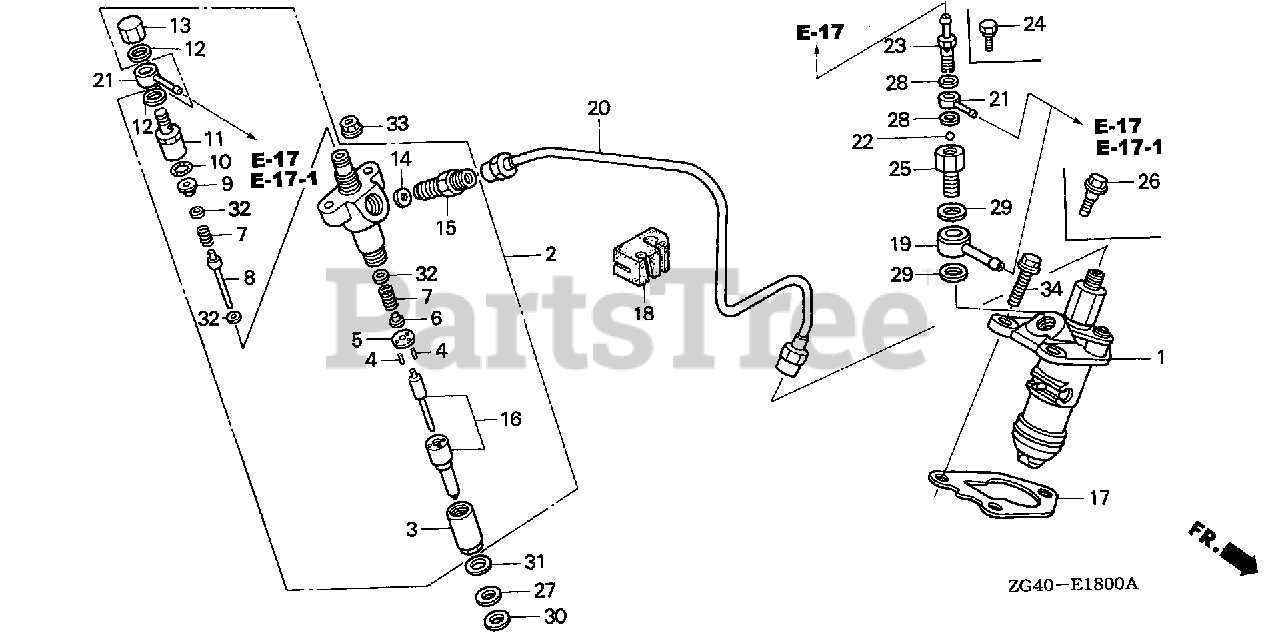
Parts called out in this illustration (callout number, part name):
1	PUMP ASSY., FUEL INJECTION
2	NOZZLE & HOLDER ASSY.
3	NUT, RETAINING
4	PIN (1.78X9.3)
6	SEAT, SPRING (A)
7	SPRING, NOZZLE
9	SEAT, SPRING (B)
15	CONNECTOR, IN.
17	GASKET, FUEL INJECTION PUMP
18	RUBBER, FUEL TUBE CLAMP
19	JOINT, FUEL
20	PIPE A, FUEL
21	JOINT, AIR BREATHER (B)
22	BALL, CHECK
23	BOLT, AIR BREATHER (8X20)
25	BOLT, FUEL JOINT (12X25.5)
26	BOLT, ROTARY TRANSMISSION
27	WASHER, PLAIN (7MM)
28	WASHER (8MM)
29	WASHER, FUEL JOINT
30	GASKET, SPECIAL (7MM)
31	GASKET A, NOZZLE (0.8)
31	GASKET B, NOZZLE (1.0)
31	GASKET C, NOZZLE (1.2)
31	GASKET D, NOZZLE (1.4)
32	SHIM A (0.50)
32	SHIM B (0.51)
32	SHIM C (0.52)
32	SHIM D (0.53)
32	SHIM E (0.54)
32	SHIM F (0.55)
32	SHIM G (0.56)
32	SHIM H (0.57)
32	SHIM I (0.58)
32	SHIM J (0.59)
32	SHIM K (0.60)
32	SHIM L (0.70)
32	SHIM M (0.80)
32	SHIM N (0.90)
33	NUT, FLANGE (6MM)
34	BOLT, FLANGE (8X25)
